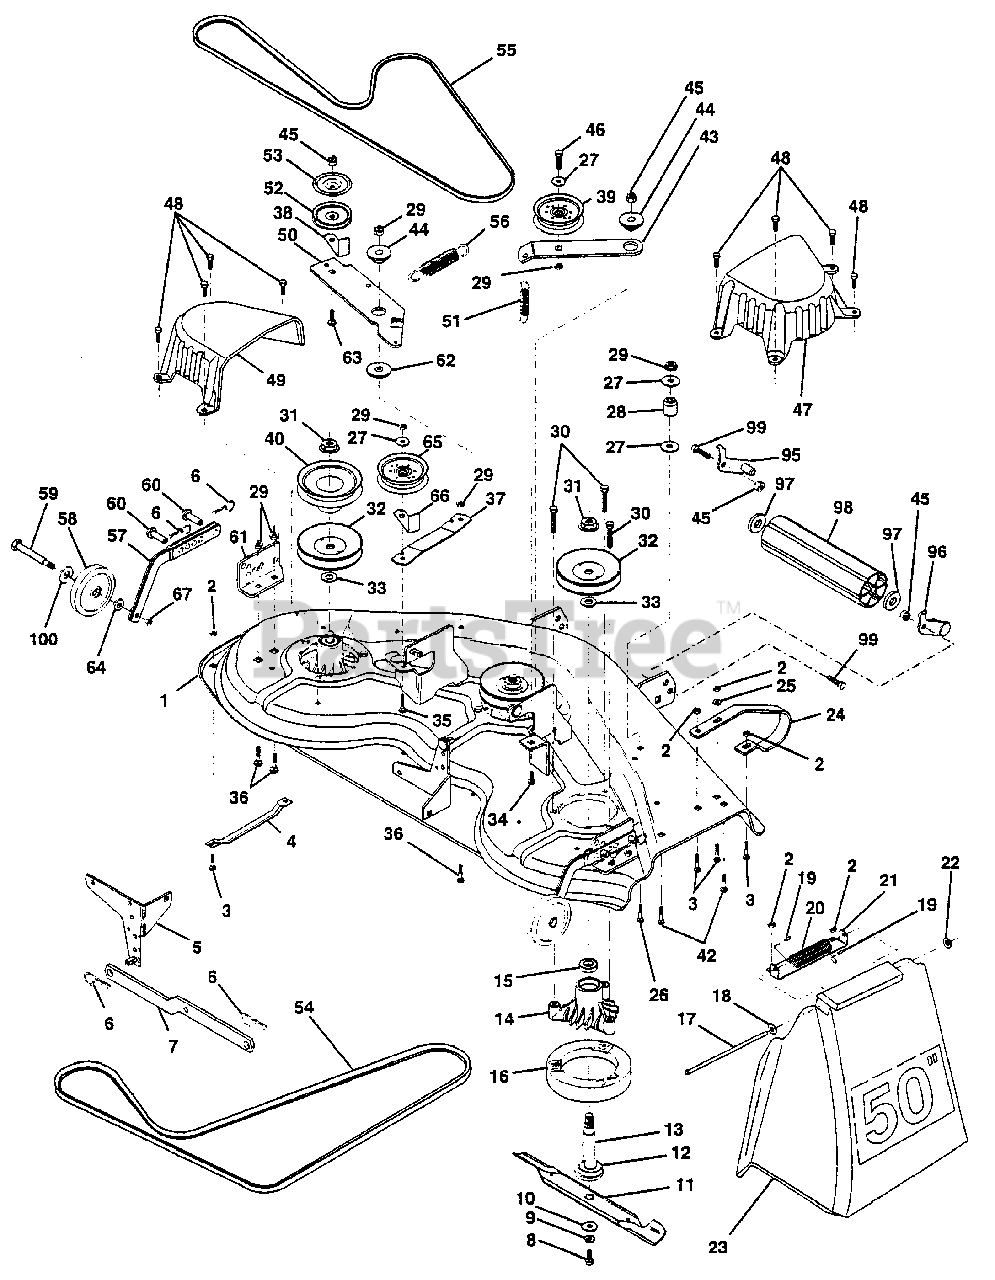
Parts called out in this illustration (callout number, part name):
1	Deck Asm., Mower 50" Vented
2	Locknut, Hex W/Ins 5/16-18 Unc
3	Bolt, Carriage 5/16-18 x 3/4
4	Runner, Mower LH
5	Bracket Asm., Sway Bar
6	Retainer, Spring
7	Arm Suspension, Rear
8	Bolt 3/8-24 x 1.25 Gr. 8 Patched
9	Washer, Lock Hvy 3/8 Unplated
10	Washer, Hard Blade Mower Vented
11	Blade
12	Bearing, Ball #6204 (Mandrel)
13	Shaft Asm., W/Lower Brg
14	Housing, Mandrel 50" Vent
15	Bearing, Ball Mandrel
16	Stripper, Mower Vented
17	Rod, Hinge
18	Washer 11/32 x 5/8 x 16 Ga.
19	Cap, Sleeve
20	Spring, Torsion Deflector
21	Bracket, Deflector
23	Shield, Deflector Mower
24	Runner, RH
25	Washer 11/32 x 3/4 x 16 Ga.
26	Bolt, Carriage 3/8-16 x 1-3/4 Gr. 5
27	Washer 13/32 x 13/16 x 16 Ga.
28	Spacer, Spring Stop Idler
29	Nut, Lock Hex W/Wsh 3/8-16 Unc
30	Screw Thdrol Hex Head
31	Nut, Fig Top Lock Cntr 9/16
32	Pulley, Mandrel
33	Washer, Spacer Mower Vented
34	Bolt, Carriage 3/8-16 x 1-1/4
35	Bolt, Carriage 3/8-16 x 2
36	Bolt, Carriage 3/8-16 x 1 Gr. 5
37	Stiffener, Arm Idler
38	Keeper, Belt Idler
39	Pulley, Idler Flat
40	Pulley, Driven
42	Bolt, Carriage 5/16-18 Unc x 3/4
43	Arm, Idler Secondary
44	Spacer, Retainer
45	Nut, Crownlock 3/8-16 Unc
46	Bolt, Fin Hex 3/8-16 Unc x 1-3/4
47	Cover, Mandrel RH
48	Screw, Thd Roll 1/4-20 x 5/8
49	Cover, Mandrel LH
50	Arm, Idler Primary
51	Spring, Secondary
52	Pulley, Idler V Groove
53	Shield, Idler
54	V-Belt, Mower Primary
55	V-Belt, Mower Secondary
56	Spring, Primary
57	Bar Asm., Wheel Gauge
58	Wheel, Gauge
59	Bolt, Shoulder
60	Pin, Clevis
61	Bracket, Wheel Gauge
62	Washer Hardened
63	Bolt Carriage 3/8-16 x 1-1/2
64	Washer 3/8 x 7/8 x 14 Ga.
65	Pulley Idler Flat Mower
66	Keeper, Belt Idler 50" Vent
67	Nut, Center Lock 3/8-16
95	Bracket, Asm. Noseroller LH
96	Bracket, Asm. Noseroller RH
97	Washer 17/32 x 7/8 x 16 Ga.
98	Roller, Nose
99	Bolt, Fin Hex 3/8-16 x 1
100	Washer 17/32 x 15/16 x 12 Ga.
